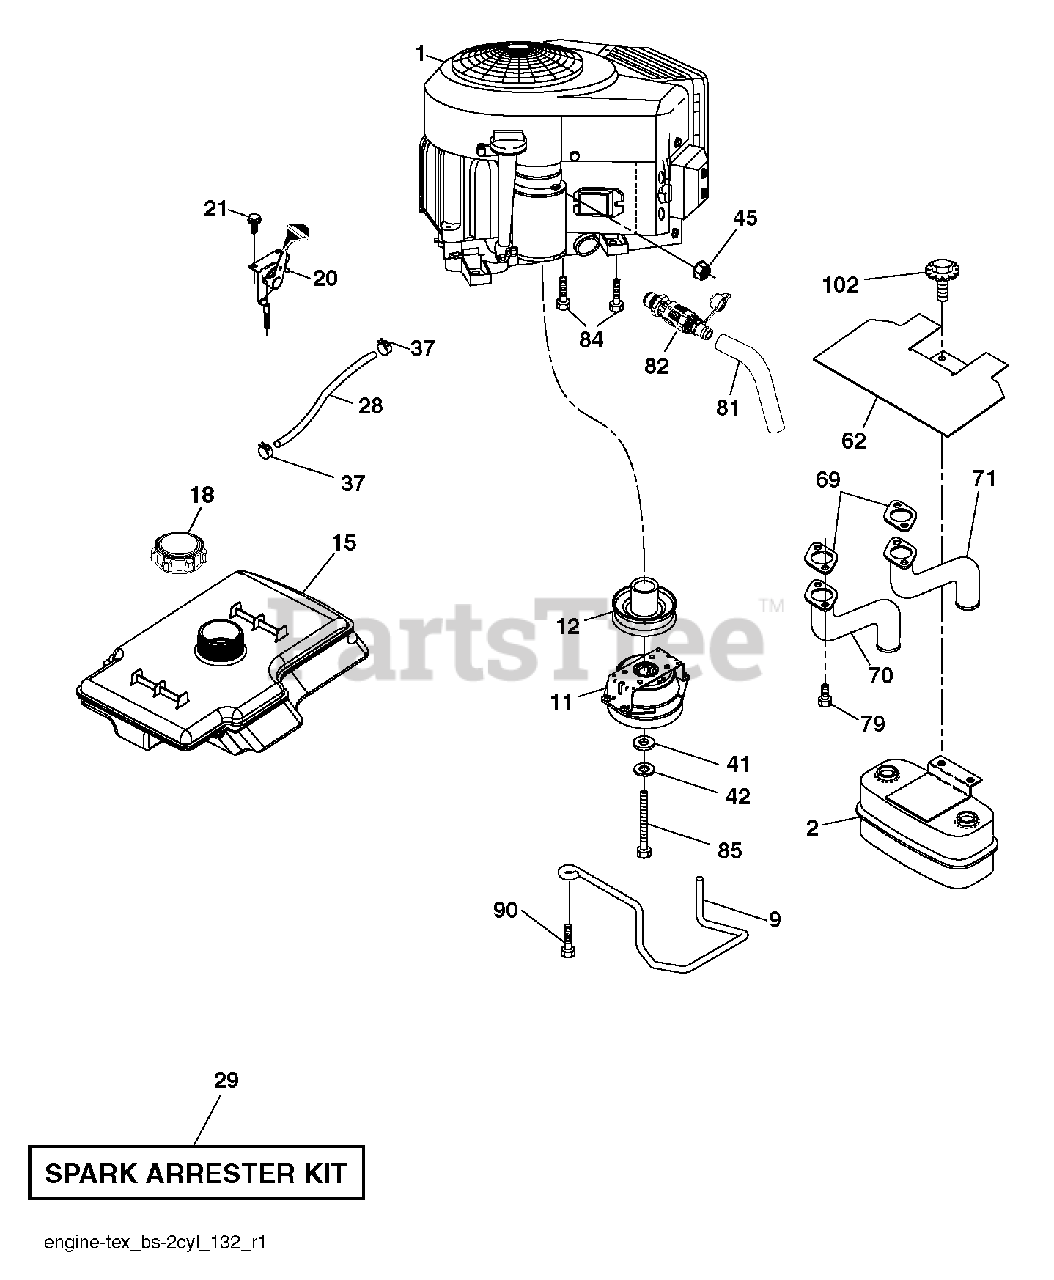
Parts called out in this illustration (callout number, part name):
2	MUFFLER.ASM.TWN.EXTNDED.DFLCTR
9	KEEPER BELT ENGINE
11	CLUTCH.OGURA.4.4PD.GT1.5-EH13V
12	PULLEY.ENGINE.TUFFTORQ
15	FUEL TANK
18	CAP.ASSY.FUEL.3".N-EPA.BLK.428
20	THROTTLE.COBRA.38"READSTART.BK
21	SCREW.#10 X 0.750.BOS
28	REPL BY 532 00 85-43
29	KIT.SPARK ARRESTOR 794945 B&S
37	HOSE CLAMP
42	LOCKWASHER
45	NUT
62	SHIELD.HEAT.MUFFLER
69	GASKET.MUFFLER
70	EXHAUST.TUBE.LH.BS/TWIN
71	EXHAUST.TUBE.RH.B&S.TWIN.INTEK
79	SCREW.SOCKET.HEAD.5/16-18
81	TUBE, DRAIN OIL ASM.
82	VALUE.OIL.DRAIN
84	SCREW.3/8-16
85	CLUTCH BOLT7/16-20X3.5 GR524HR
90	SCREW 3/8-16X1
102	SCREW
